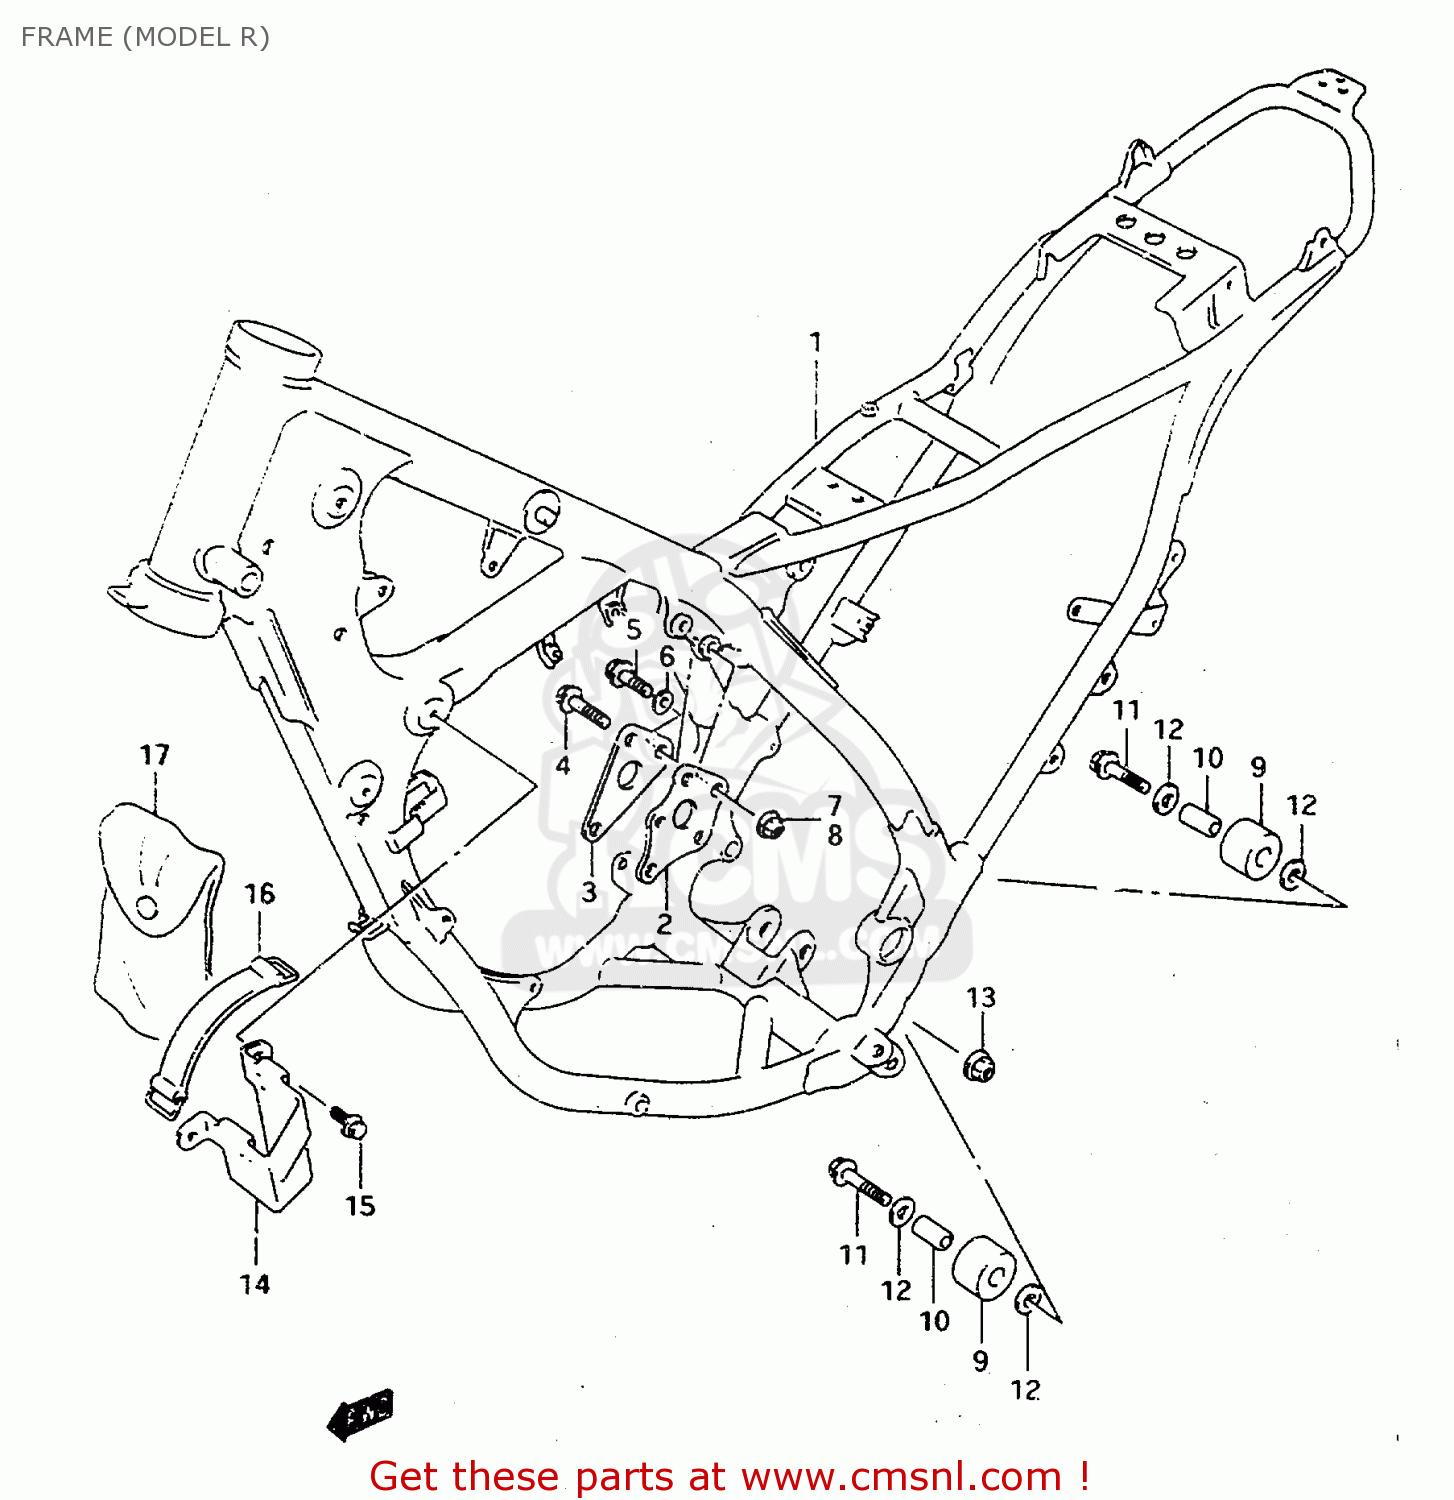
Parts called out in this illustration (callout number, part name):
1	FRAME (WHITE)
2	PLATE,ENG MTG,L
3	PLATE,ENG MTG,R
4	BOLT
5	BOLT
6	WASHER
7	NUT
8	NUT
9	ROLLER,CHAIN CONTROL
10	BOLT(8X45)
11	WASHER
12	NUT
13	NUT
14	BOLT 6X12
15	BOLT
16	BAND
17	TOOL ASSY
